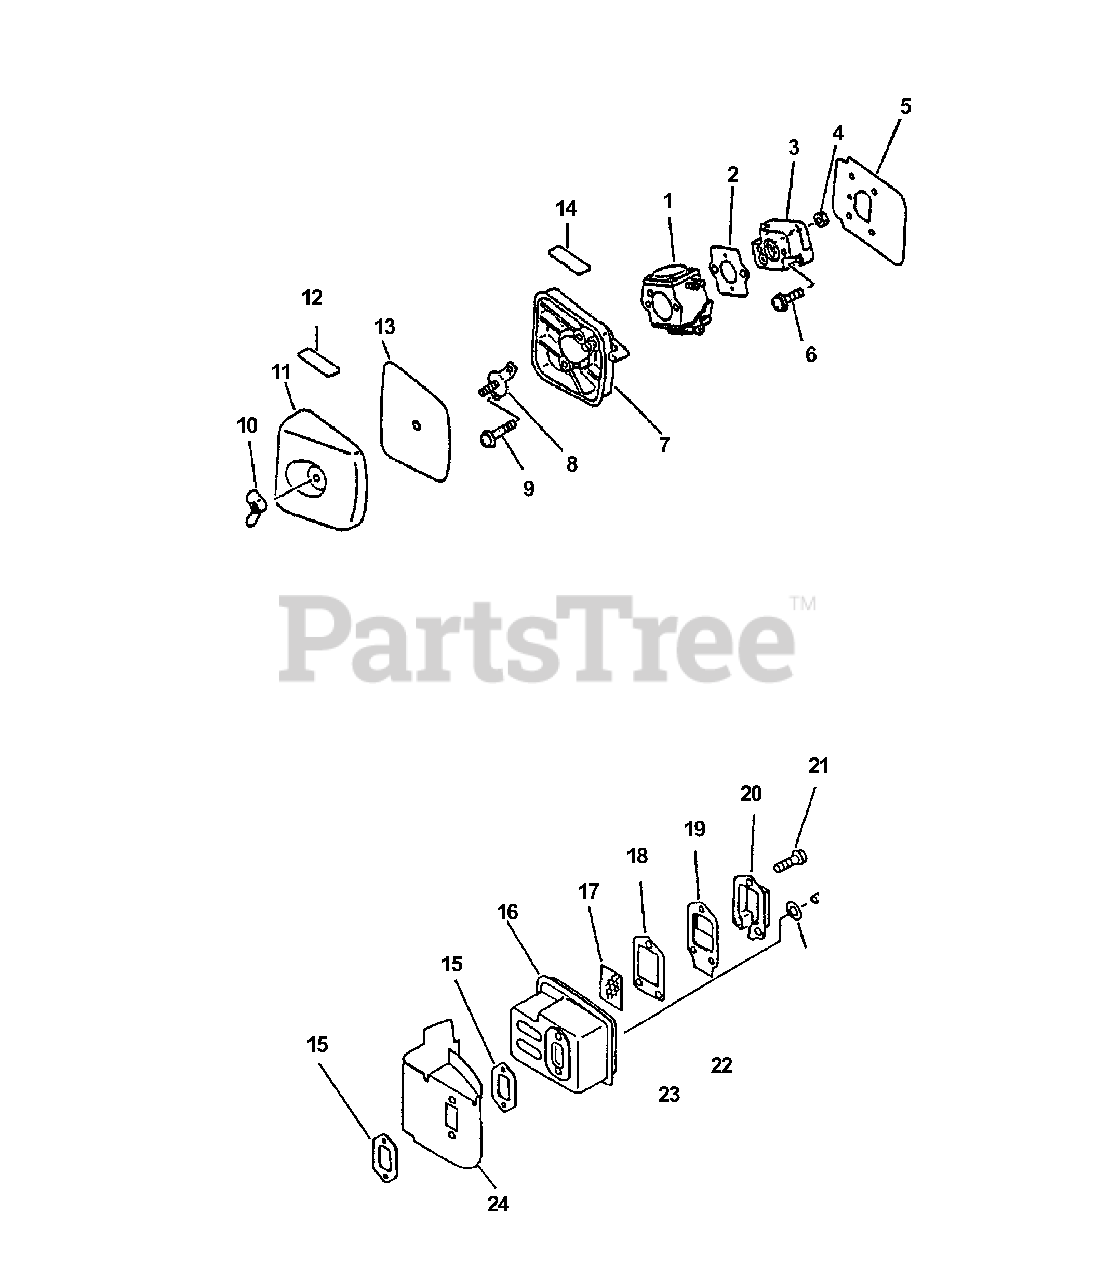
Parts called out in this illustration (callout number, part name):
1	CARBURETOR WT-168A
1	CARBURETOR C1U-K18
2	GASKET, INTAKE
3	INSULATOR, INTAKE
5	SHIELD, INTAKE
6	SCREW - 5X20
7	CASE, AIR FILTER
7	AIR FILTER CASE KIT - BLACK
8	PLATE, PREVENT
9	SCREW - 5X64
10	WINGNUT - 6
11	COVER, AIR FILTER
12	LABEL - TOP
13	FILTER, AIR
14	LABEL - CHOKE
15	GASKET, EXHAUST
17	SCREEN, SPARK ARRESTOR
18	GASKET, EXHAUST
19	GASKET, EXHAUST - INNER
20	GUIDE, EXHAUST - OUTER
21	SCREW - 4X10
22	SCREW - 5X55
23	WASHER - 5
24	COVER, EXHAUST
